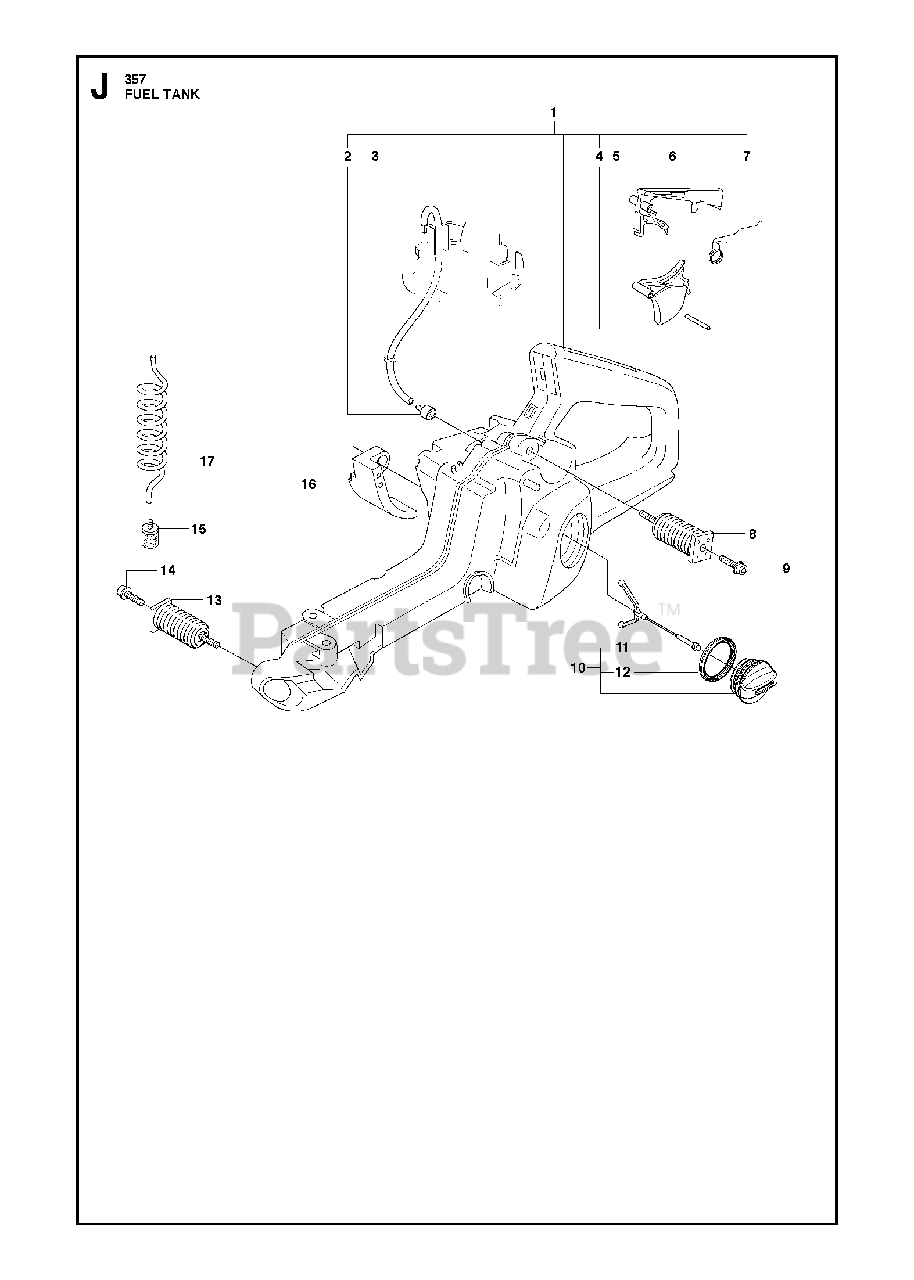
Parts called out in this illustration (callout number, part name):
1	FUEL TANK W/ ACCESSORIES
2	FUEL TANK VENT
3	FUEL HOSE
4	PIN
5	TRIGGER
6	THROTTLE LOCK
7	SPRING
8	VIBRATION ABSORBER
10	TANK CAP
11	TANK LOCK
12	SEALING
15	FUEL FILTER
17	FUEL HOSE
